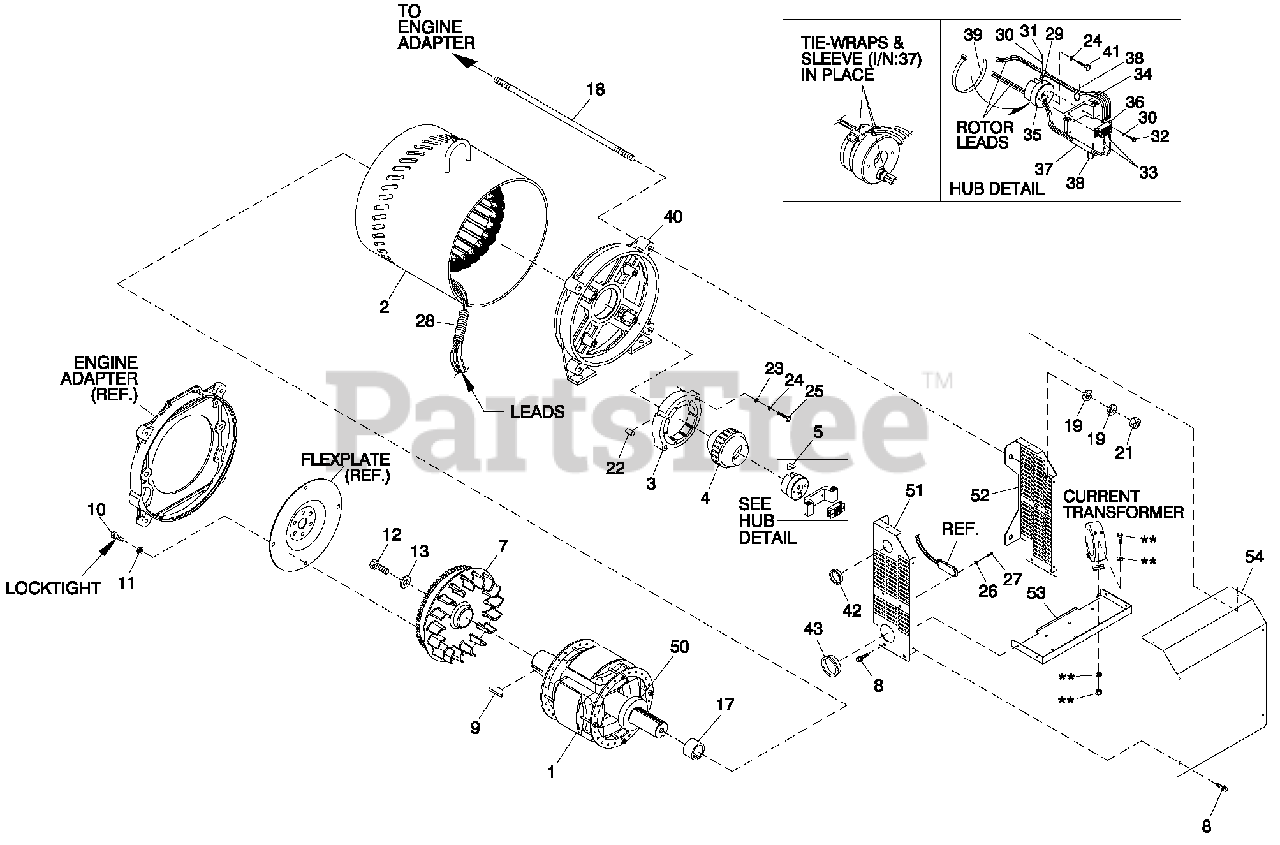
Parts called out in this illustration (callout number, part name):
1	ROTOR 390 70AB3 CPL
2	STATOR 390 70AB3 CPL
3	EXITER FIELD 2" LG SPD CONN
4	ASSY EXCITER 2.00" STK
5	KEY SQ 3/8 X 3-1/4 STEEL
7	ASSY FLYWHEEL CPL
8	SCREW THF M6-1 X 16 N WA Z/JS
9	KEY WOODRUFF #E
10	SCREW HHC M10-1.50 X 16 G10.9
11	WASHER LOCK M10
12	SCREW HHC M16-2.0 X 45 G8.8
13	SPACER .69 X 2.75 X .37 ST/ZNC
14	WASHER FLAT 1/4-M6 ZINC
15	WASHER LOCK M6-1/4
16	SCREW HHC M6-1.0 X 16 G8.8
17	COLLAR SLIP FIT 390 MM
18	STUD M14-2.0X 650 G5 ZINC
19	WASHER FLAT M14
20	WASHER LOCK M14
21	NUT HEXM14-2.0 G8 YEL CHR
22	PIN DOWEL 1/2 X 1-1/4
23	WASHER FLAT M12
24	WASHER LOCK M12
25	SCREW HHC M12-1.75 X 80 G10.9
26	SCREW PHTT #6-32 X 1/2 ZYC
27	WASHER LOCK #6
28	CONDUIT FLEX 1.25" ID
29	CLAMP VINYL .312X.203Z
30	WASHER SHAKEPROOF INT #8
31	SCREW HHM #8-32 X 3/8
32	SCREW HHM #8-32 X 7/8
33	LUGRT-ANG #10/10-12
34	BRIDGE SUPPORT DIODE 15"
35	CAP END ROTOR 390MM
36	ASSY BRIDGE RECTIFIER
37	SLEEVING UL #0.330 ID (3" LG)
38	TIE WRAP UL 3.9" X .10" BLK
39	TIE WRAP UL 17.7 X .35 BLK HT
40	REAR BEARING CARRIER CPL
41	SCREW HHC M12-1.75 X 60 G10.9
42	BUSHING SNAP SB-1750-22
43	BUSHING SNAP SB-2.5-31
50	BEARING BALL 6212 SEALED
51	SIDE LH EXCITER SHIELD
52	SIDE RH EXCITER SHIELD
53	BOTTOM EXCITER SHIELD
54	REAR COVER EXCITER SHLD
